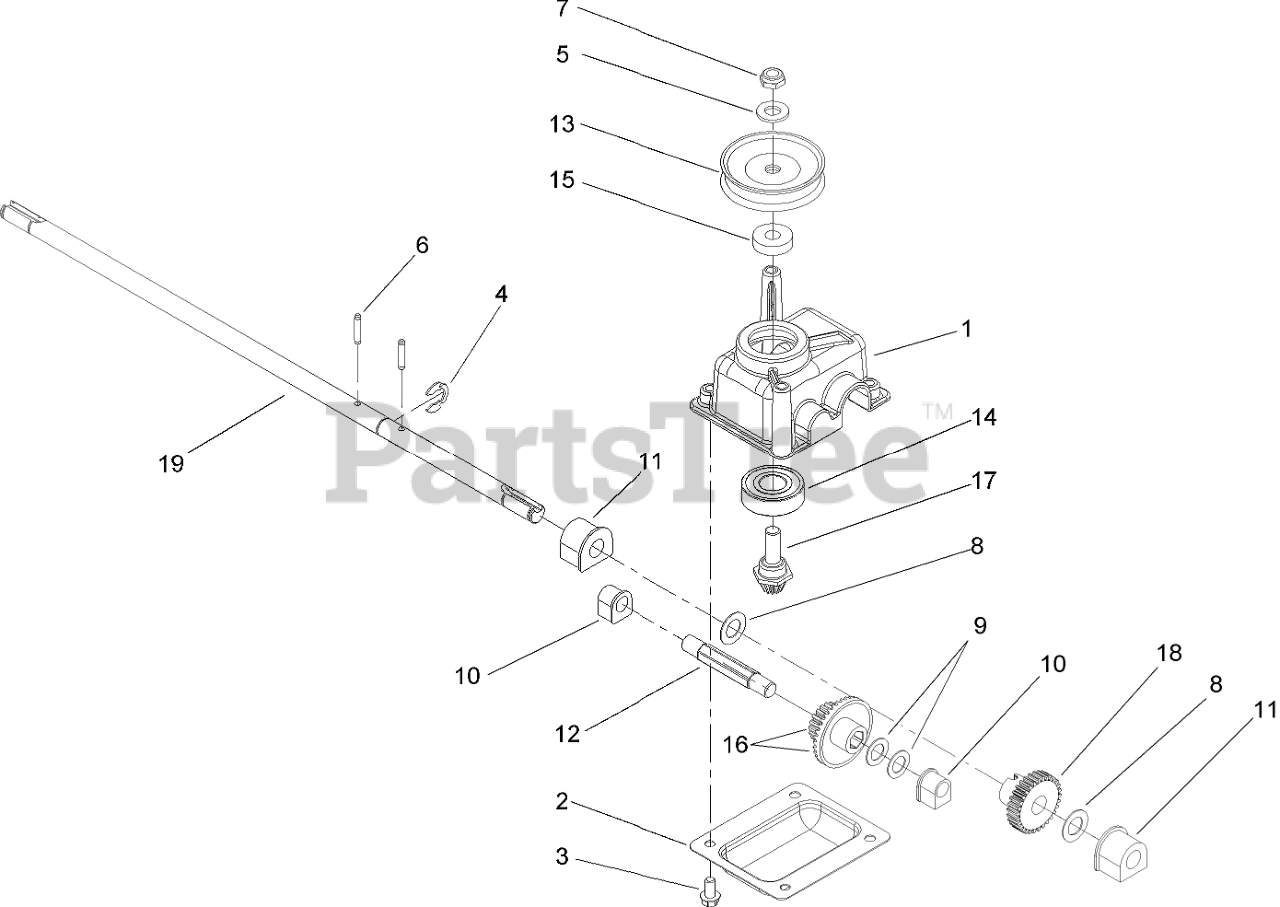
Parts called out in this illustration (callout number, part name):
1	CASE-GEAR
2	COVER-CASE, GEAR
3	SCREW-HWH
4	RING-RETAINING
5	WASHER-FLAT
6	PIN-GROOVE
7	NUT-HEX
8	WASHER-PLAIN
9	WASHER-THRUST
10	BUSHING
11	BUSHING
12	SHAFT-INTERMEDIATE
13	PULLEY-HALF
14	BEARING-BALL
15	SPACER
16	GEAR-19T SPUR, 37T BEVEL
17	GEAR-PINION, BEVEL
18	GEAR-30T
19	SHAFT-OUTPUT
